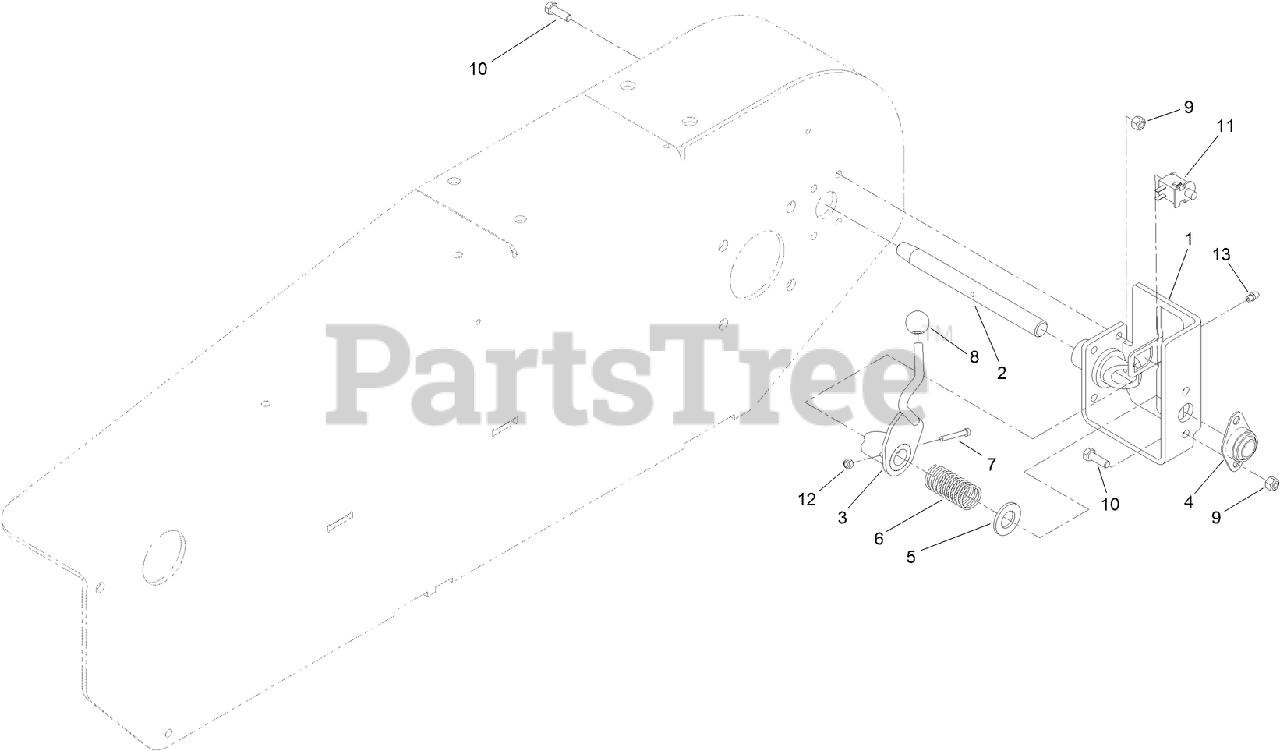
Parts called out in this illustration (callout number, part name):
1	BRACKET-BRAKE
2	SHAFT-BRAKE
3	HANDLE-BRAKE
4	BEARING
5	WASHER-FLAT
6	SPRING-COMPRESSION
7	SCREW-HSH
9	NUT-LOCK, NI
10	SCREW-HH
11	SWITCH
12	NUT-LOCK, NI
13	FITTING-GREASE
